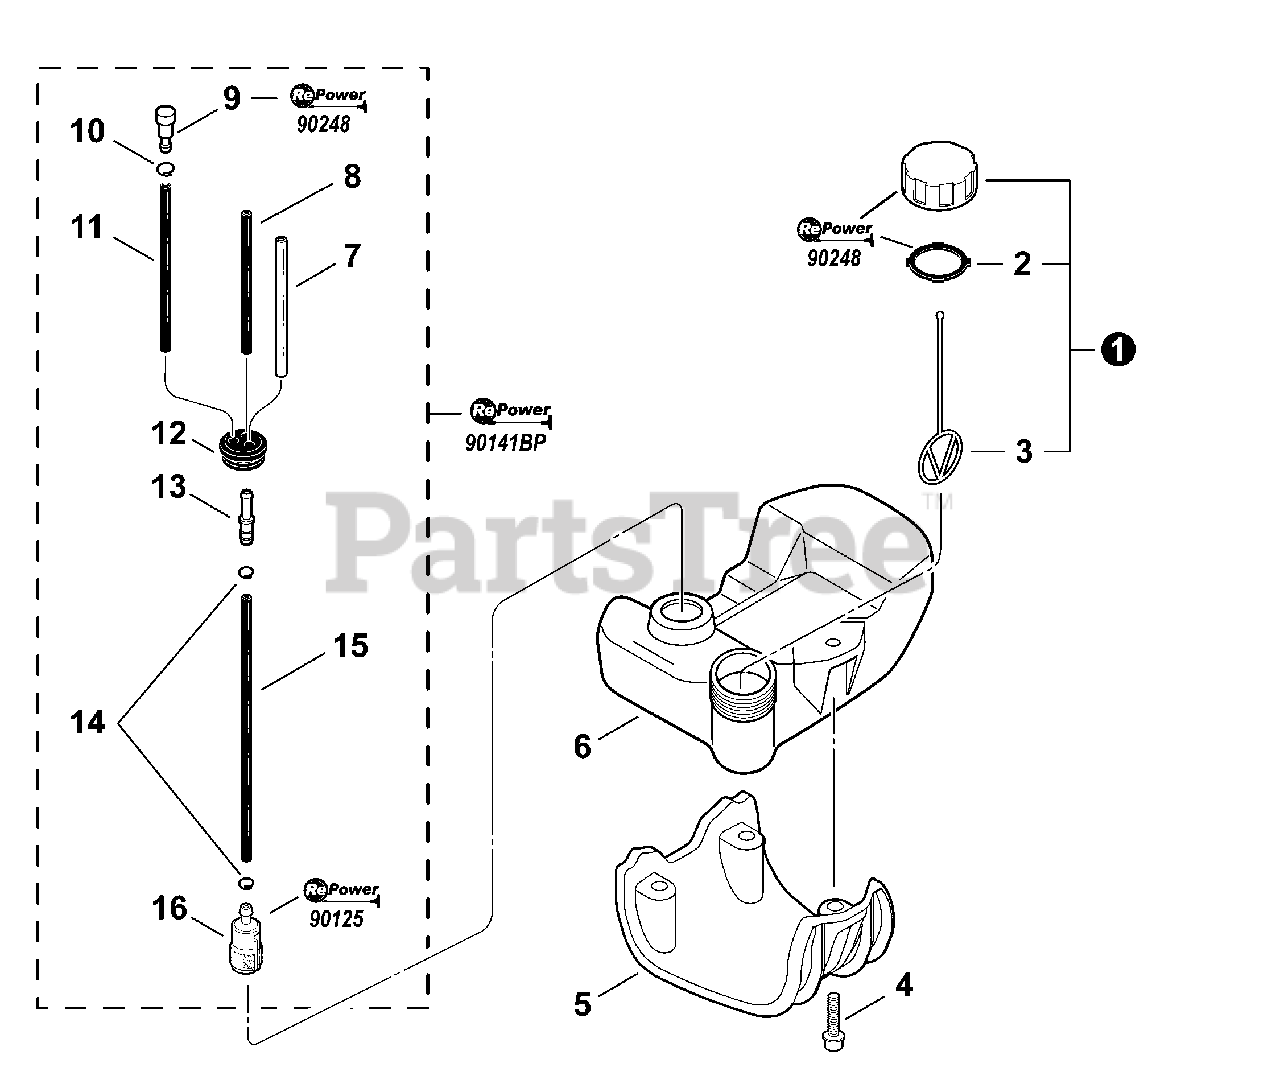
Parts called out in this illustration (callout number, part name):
1	CAP ASY - ORANGE
2	GASKET, CAP
3	CONNECTOR, CAP
4	SCREW - 5×20
5	GUARD, FUEL TANK
6	TANK, FUEL
7	PIPE - 3×6×80 -- CLEAR
8	PIPE - 3×5×67 -- BLACK
9	VENT, FUEL TANK
10	CLIP - 6.5
11	PIPE - 3×6×115 -- BLACK
12	GROMMET
13	CONNECTOR, FUEL PIPE
14	CLIP - 6
15	PIPE - 3×5×125 -- BLACK
16	FILTER, FUEL
